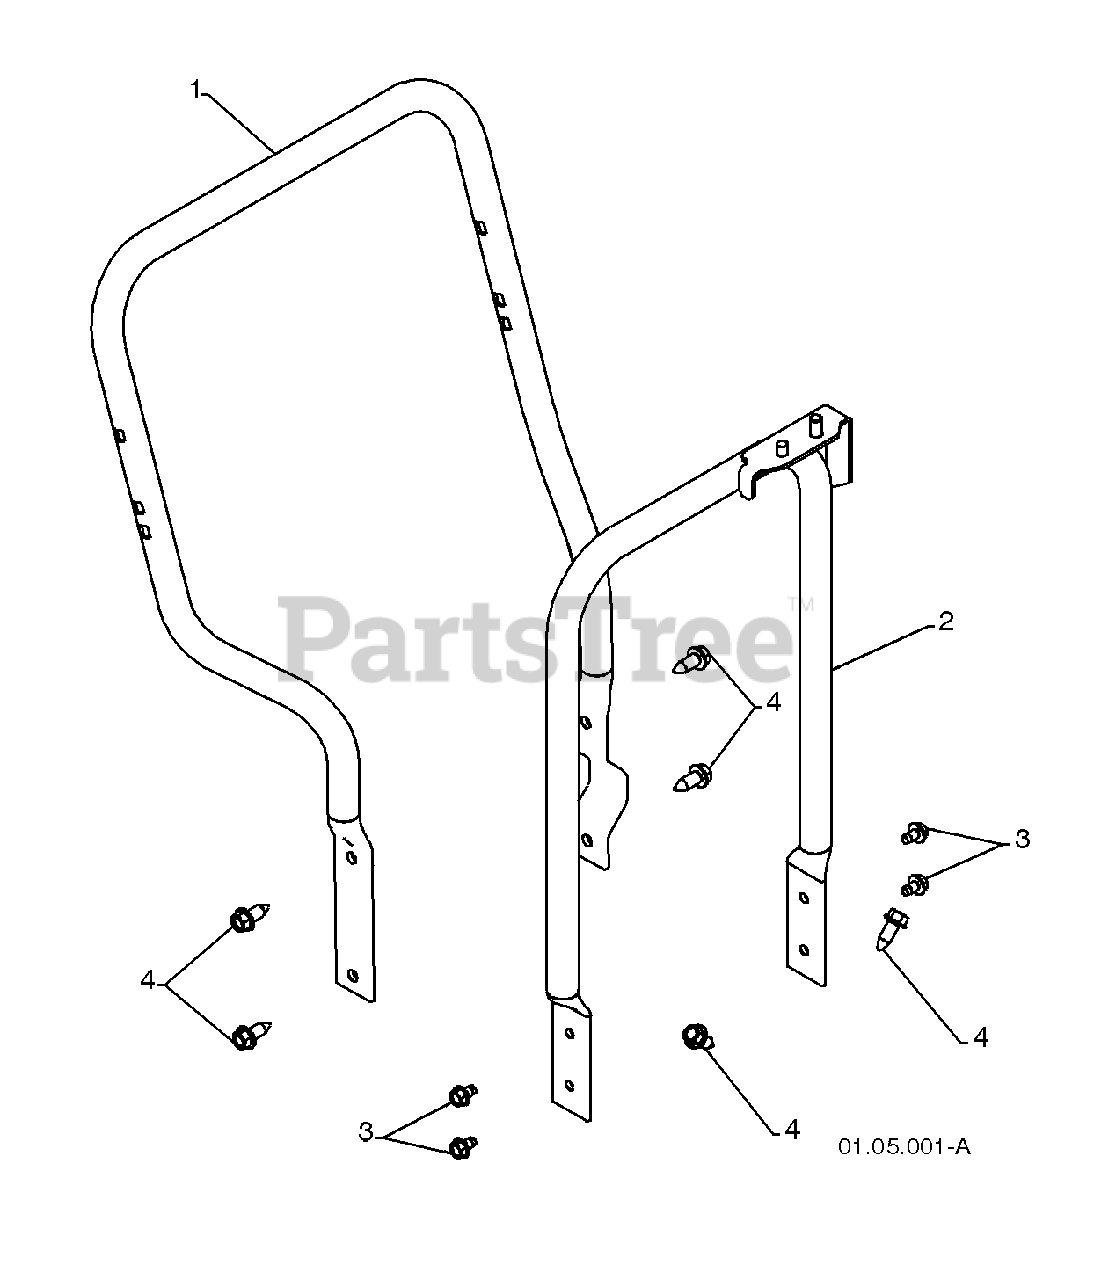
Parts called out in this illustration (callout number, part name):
1	LOWER TUBE
2	PIVOT SUPPORT
3	BOLT 5/16-18 X .500
4	SCREW 3/8-16 X 1.00
